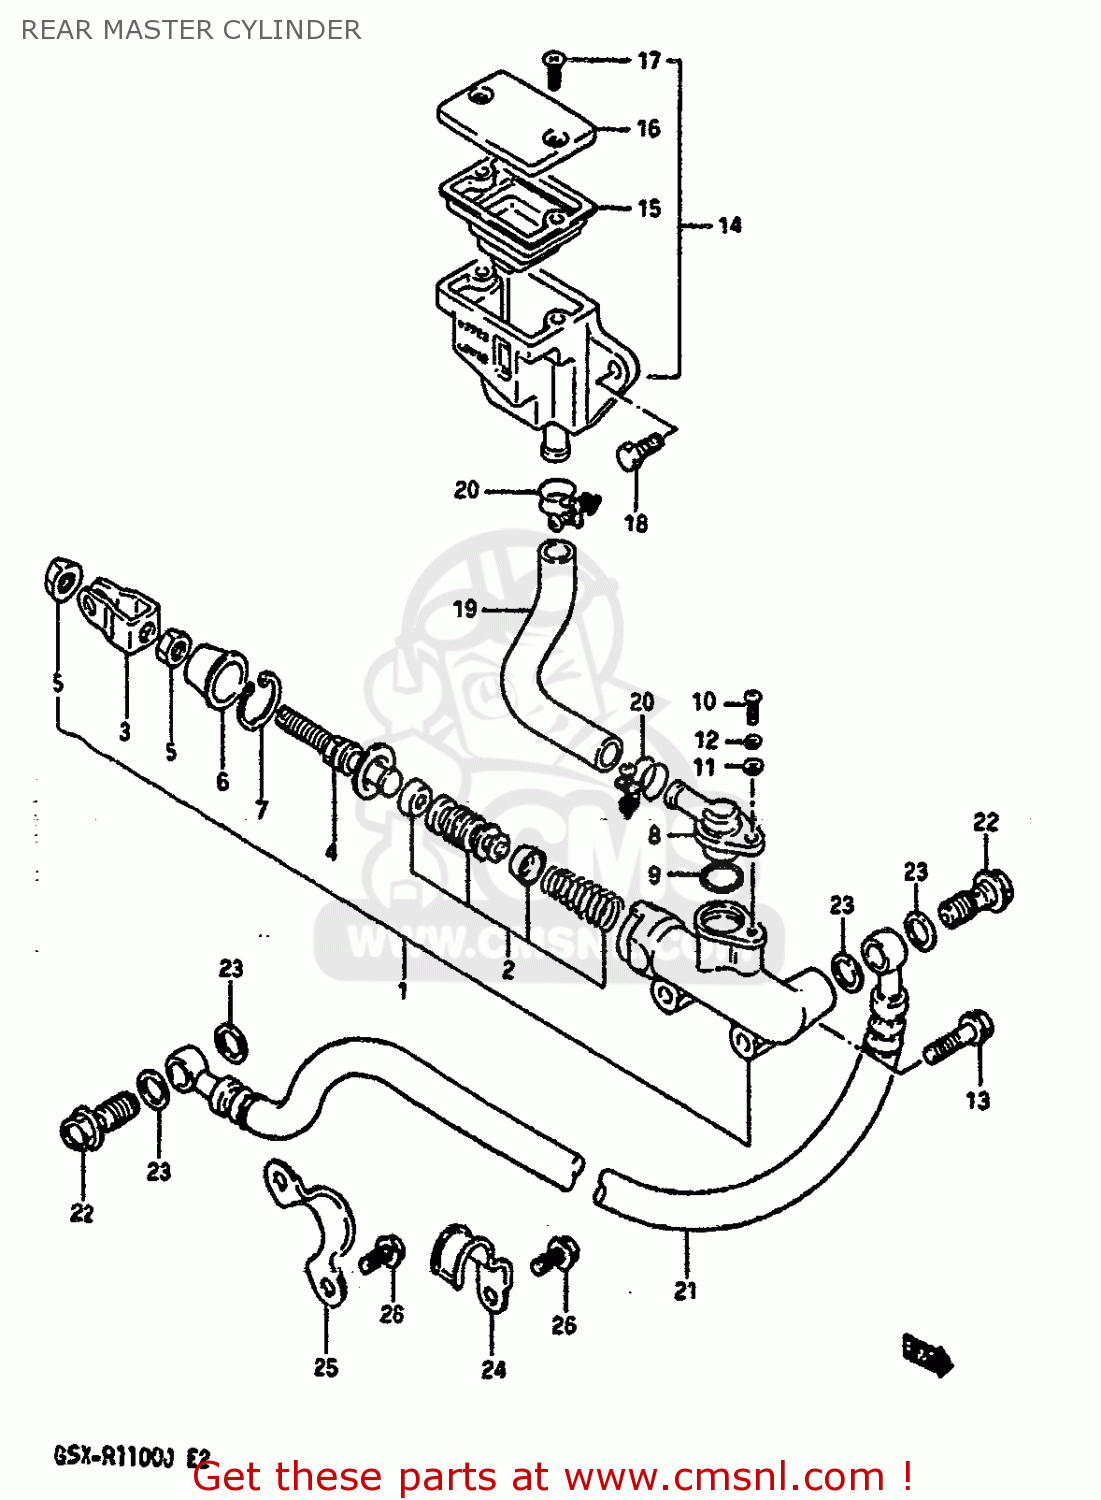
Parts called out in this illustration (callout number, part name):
1	CYLINDER ASSEMBLY,REAR MASTER
2	PISTON/CUP SET
3	YOKE
4	ROD,PUSH
5	NUT
6	BOOT
7	CIRCLIP
8	CONNECTOR
9	O RING
10	SCREW
11	WASHER
12	LOCK WASHER
13	BOLT 6X23
14	TANK ASSEMBLY,RESERVOIR
15	DIAPHRAGM
16	CAP
17	SCREW
18	BOLT
19	HOSE,RESERVOIR TANK
20	CLAMP
21	HOSE,REAR BRAKE
22	BOLT UNION
23	WASHER(10X15X1.5)
24	CLAMP,REAR BRAKE HOSE NO
25	CLAMP,REAR BRAKE HOSE
26	BOLT
